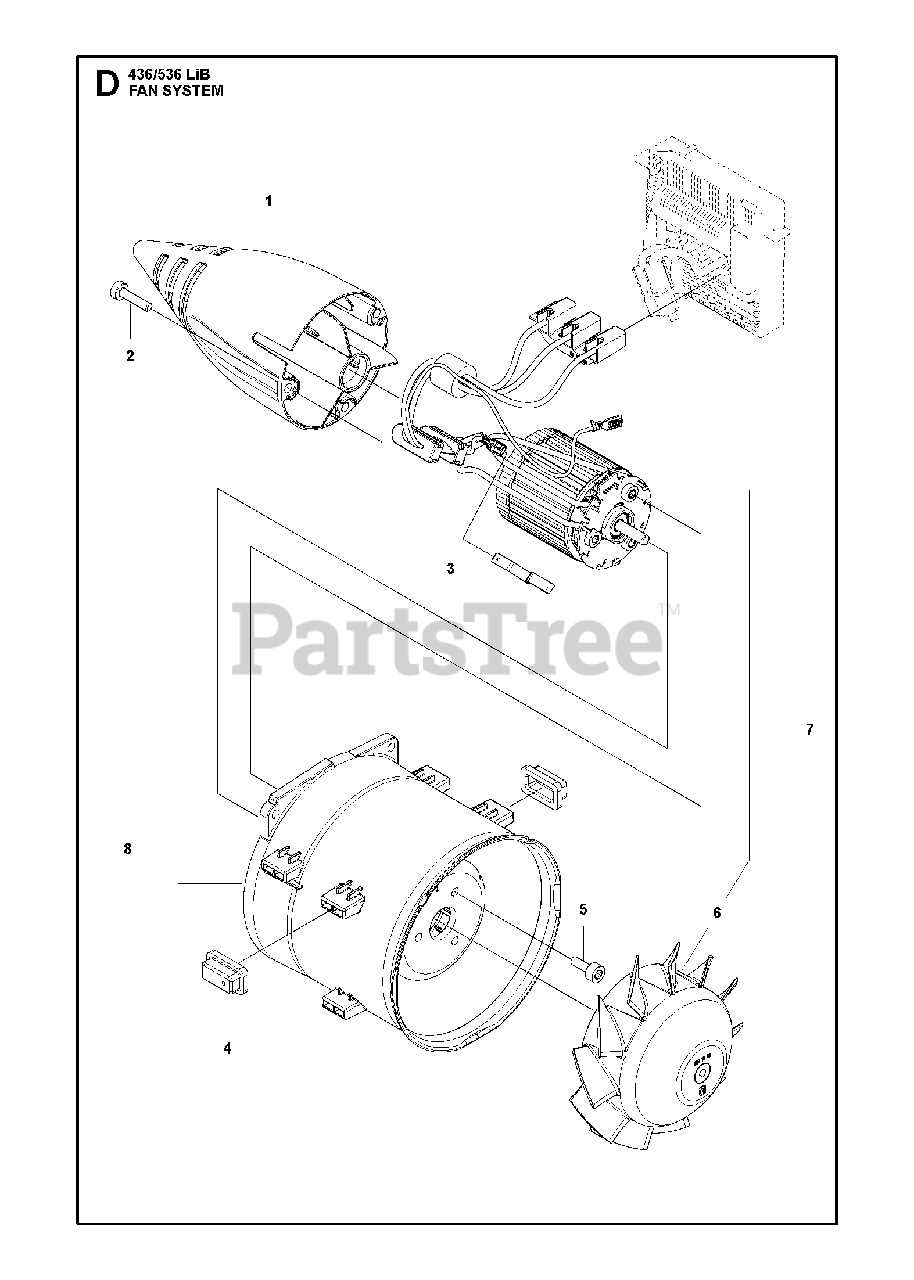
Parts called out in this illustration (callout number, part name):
1	CONE FAN OUTLET
2	SCREW
3	SPRING
6	ROTOR FAN
8	KIT STATOR
